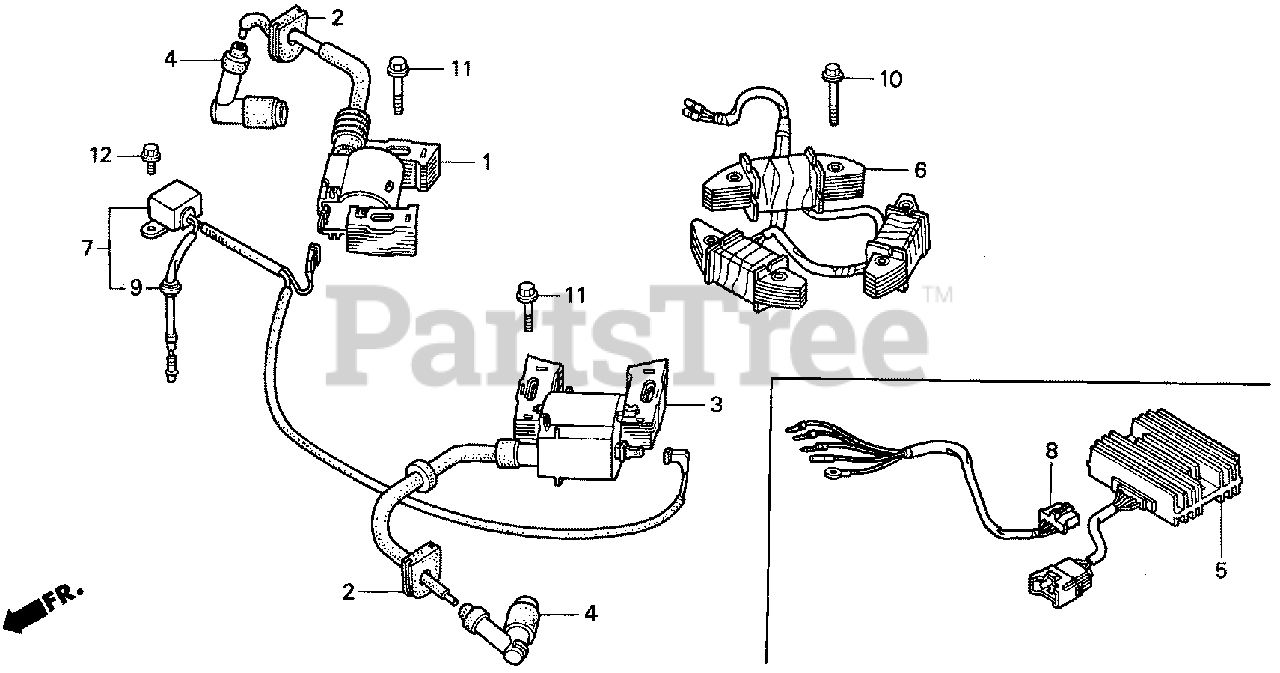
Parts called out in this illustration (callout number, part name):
1	COIL ASSY., R. IGNITION
2	GROMMET, IGNITION WIRE
3	COIL ASSY., L. IGNITION
4	CAP ASSY., NOISE SUPPRESSOR
5	RECTIFIER ASSY., REGULATOR (20A)
6	COIL ASSY., CHARGE (12V/20A)
7	DIODE ASSY., ENGINE STOP
8	SUB-WIRE HARNESS ASSY.
9	GROMMET, TOOL
10	BOLT, FLANGE (6X32)
11	BOLT, FLANGE (6X25)
12	BOLT, FLANGE (6X8)
